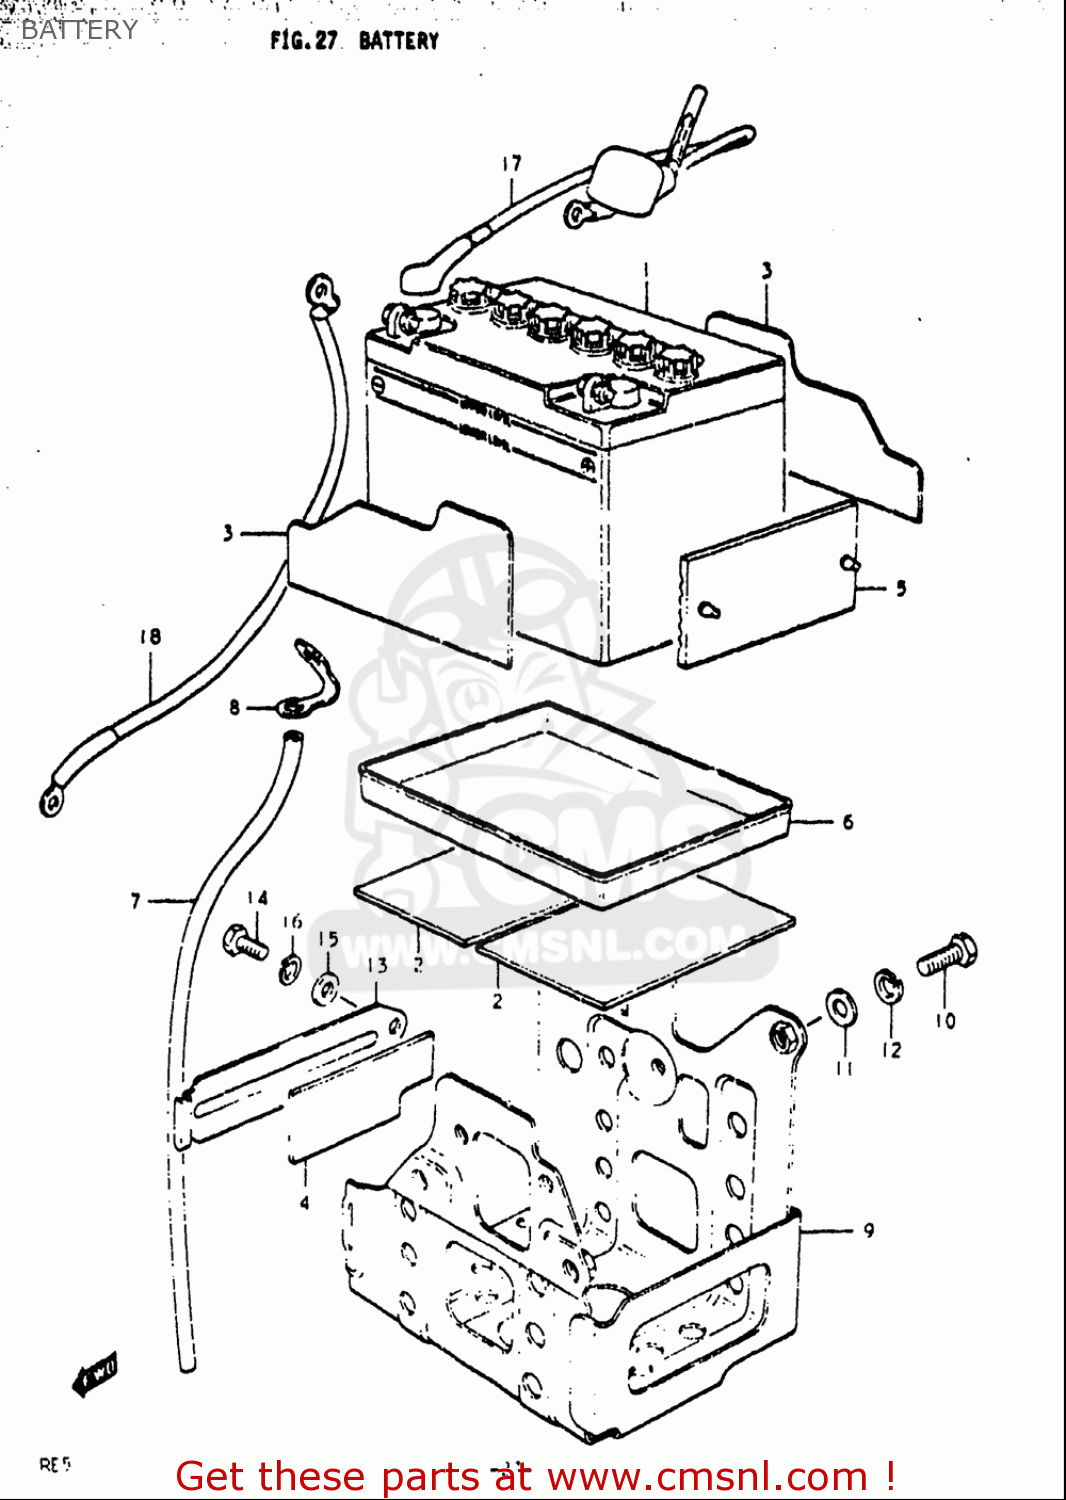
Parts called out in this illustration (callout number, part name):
3	PROTECTOR(170X95X3.0)
5	PROTECTOR,BATTERY
6	TRAY,BATTERY
7	HOSE,BATTERY EXHAUST(L:780)
8	CLAMP
10	BOLT(8X14)
11	WASHER
12	WASHER,LOCK
14	BOLT
15	WASHER
16	WASHER,LOCK
